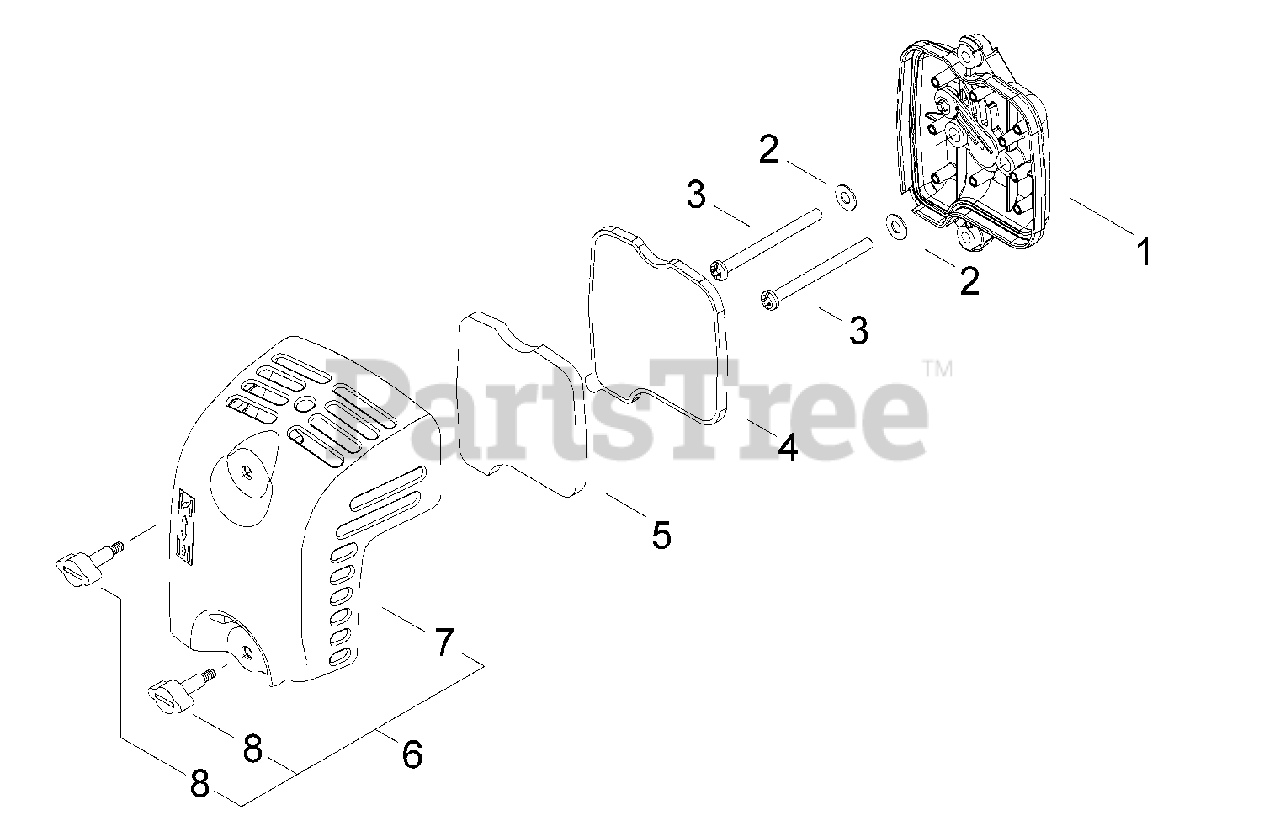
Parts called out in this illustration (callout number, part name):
1	AIR FILTER CASE ASSY
2	WASHER - 5
3	SCREW - 5X60
4	FILTER, AIR
5	PRE-FILTER - FOAM
6	AIR FILTER COVER ASSY
7	COVER, AIR FILTER
8	THUMBSCREW
